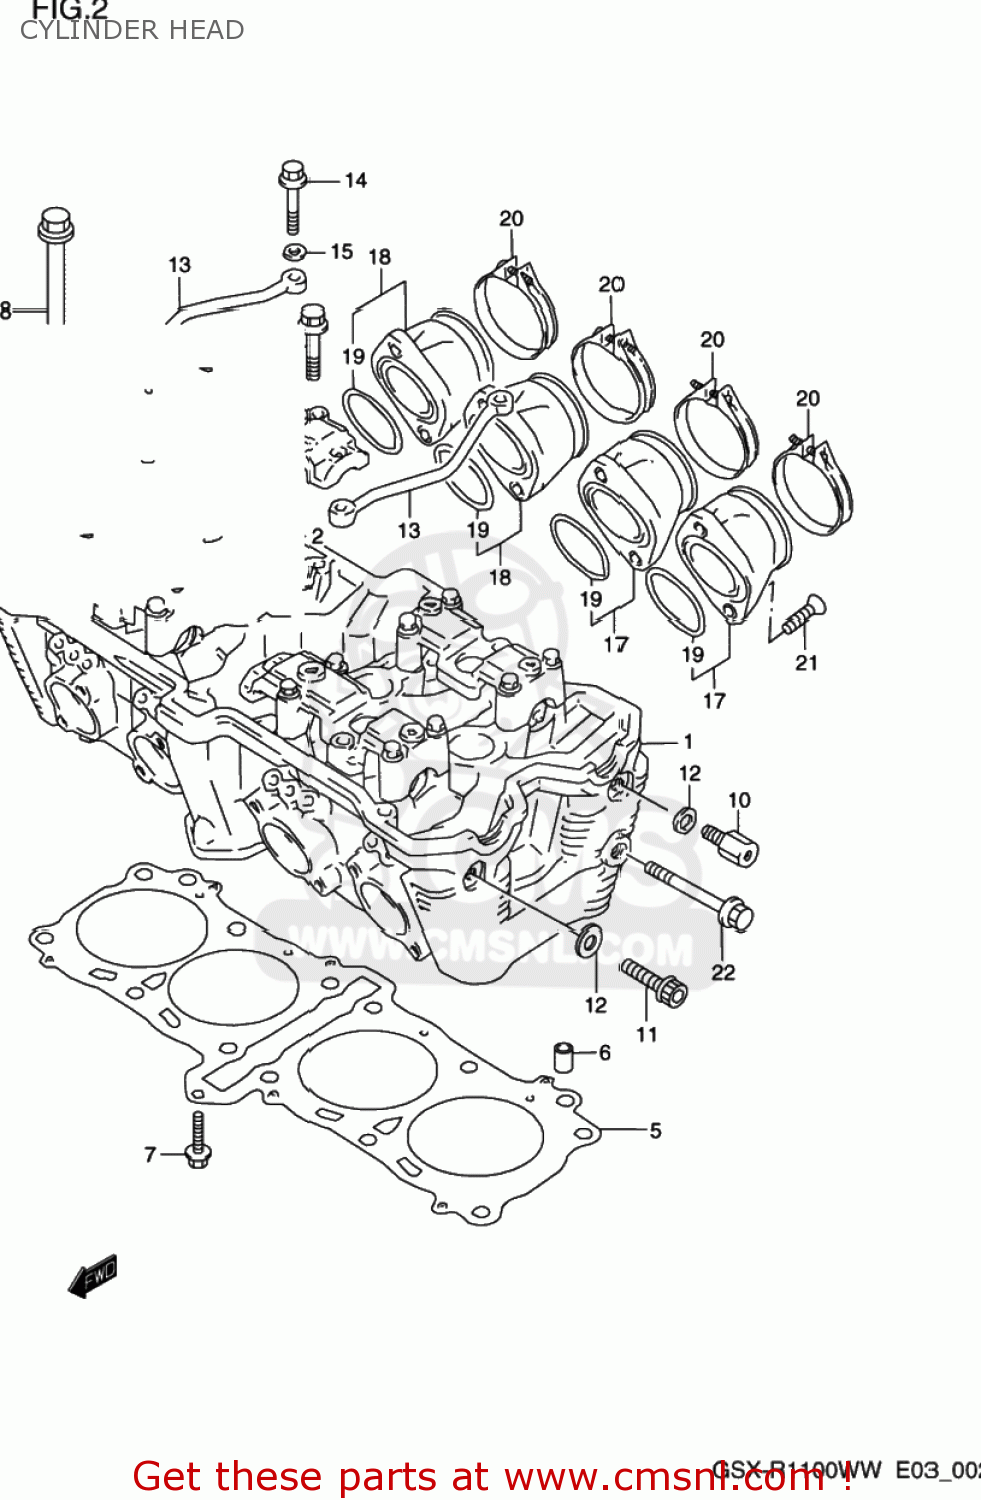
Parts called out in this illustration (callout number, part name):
1	HEAD ASSEMBLY,CYLINDER
2	GUIDE,VALVE
3	BOLT
4	PIN(6.2X8X11)
5	GASKET,CYLINDER HEAD
6	PIN
7	BOLT
8	BOLT 10X175
9	WASHER(10.5X19X2)
10	BOLT
11	BOLT
12	GASKET(8.2X14X1).6 (NAS)
13	PIPE,CYLINDER HEAD OIL
14	BOLT(6X39)
15	WASHER
16	PLUG,SPARK(CR8E)
17	PIPE ASSEMBLY,INTAKE
18	PIPE ASSEMBLY,INTAKE
19	O RING(D:2.4,ID:47X42)
20	CLAMP
21	SCREW
22	BOLT
